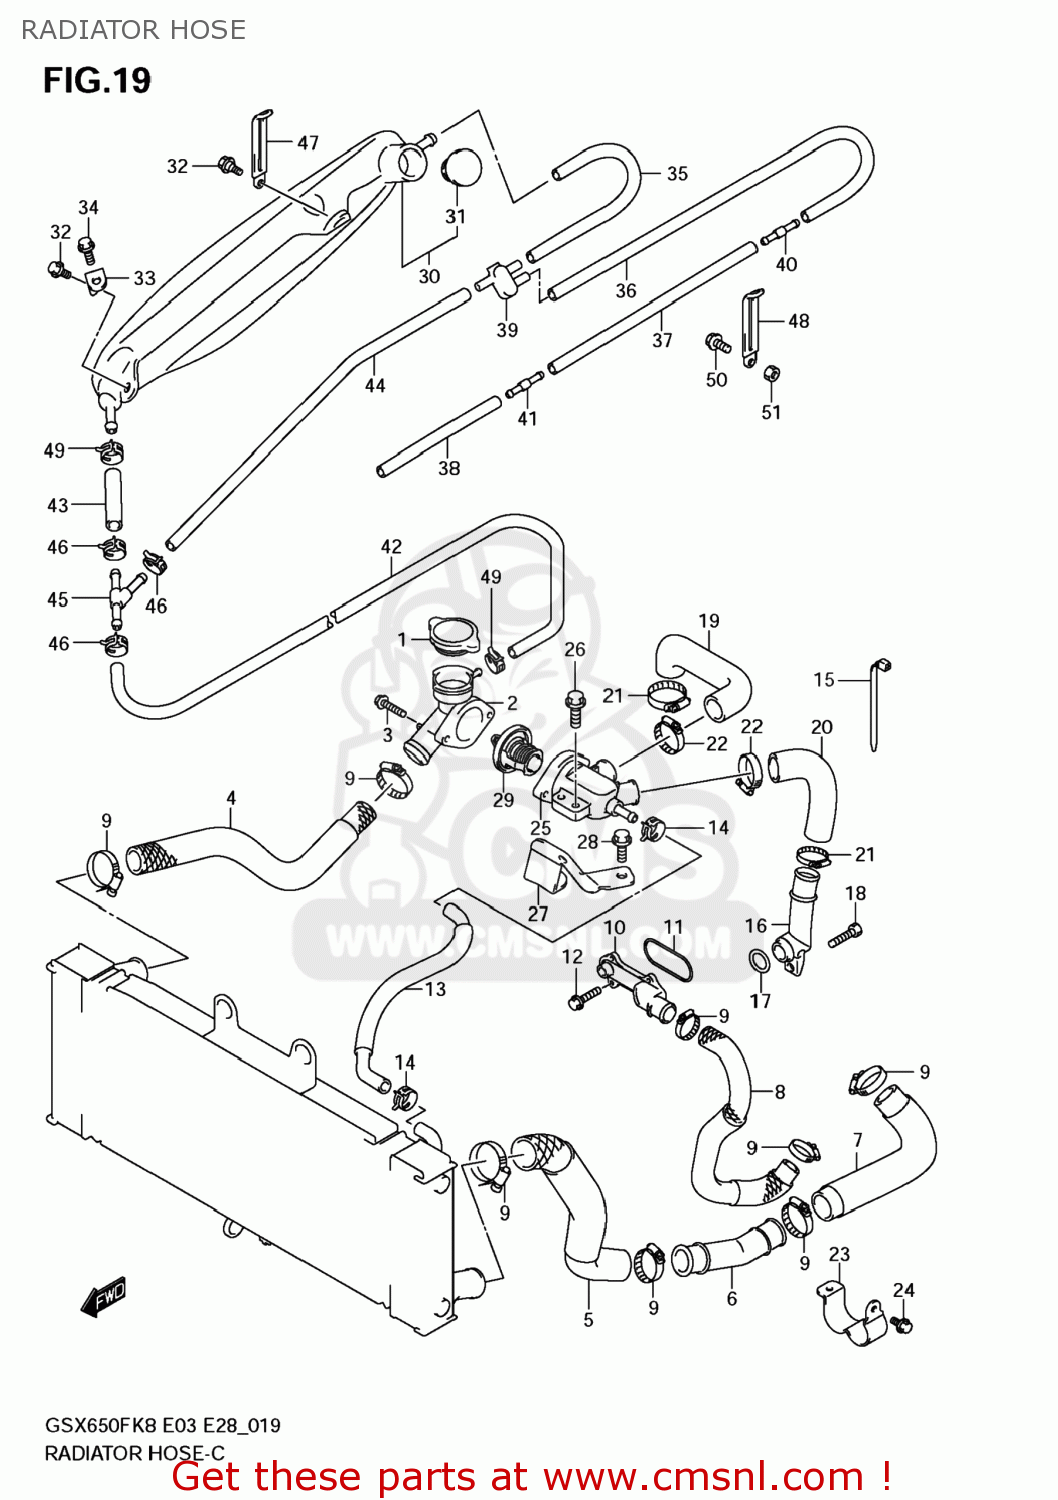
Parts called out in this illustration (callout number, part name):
1	CAP,RADIATOR(1.1)
2	CONDUCTION,RADIATOR
3	BOLT
4	HOSE,RADIATOR INLET
5	HOSE,RADIATOR OUTLET
6	PIPE,RADIATOR OUTLET
7	HOSE,WATER PUMP INLET
8	HOSE,WATER PUMP OUTLET
9	CLAMP
10	CONNECTOR,CYLINDER WATER INLET
11	O RING,CYL INLET CONNECTOR
12	BOLT
13	HOSE,WATER BYPASS
14	CLAMP
15	CLAMP(L:165)
16	PIPE,CYLINDER HEAD OUTLET
17	O RING(D:3.2,ID:17.8)
18	BOLT
19	HOSE,CYLINDER HEAD OUTLET,R
20	HOSE,CYLINDER HEAD OUTLET,L
21	CLAMP
22	CLAMP
23	PLATE,WATER HOSE CLAMP
24	BOLT
25	CONNECTOR,THERMOSTAT INLET
26	BOLT
27	BRACKET,THERMOSTAT CONNECTOR
28	BOLT
29	THERMOSTAT,WATER 82 DEG
30	TANK ASSY,RESERVOIR
31	CAP,RESERVOIR TANK
32	BOLT(6X12)
33	BRACKET,RESERVOIR TANK
34	BOLT
35	HOSE,RESERVOIR TANK OVFL
36	HOSE,RESERVOIR TANK OVFL NO.2
37	HOSE,RESERVOIR TANK OVFL NO.3
38	HOSE
39	JOINT
40	JOINT
41	JOINT
42	HOSE(5X9X2000)
43	HOSE(5X9X600)
44	HOSE(3.5X7.5X600)
45	3 WAY
46	CLIP
47	CLAMP(L:45 T:0.6)
48	CLAMP(L:45)
49	CLIP
50	BOLT
51	NUT
